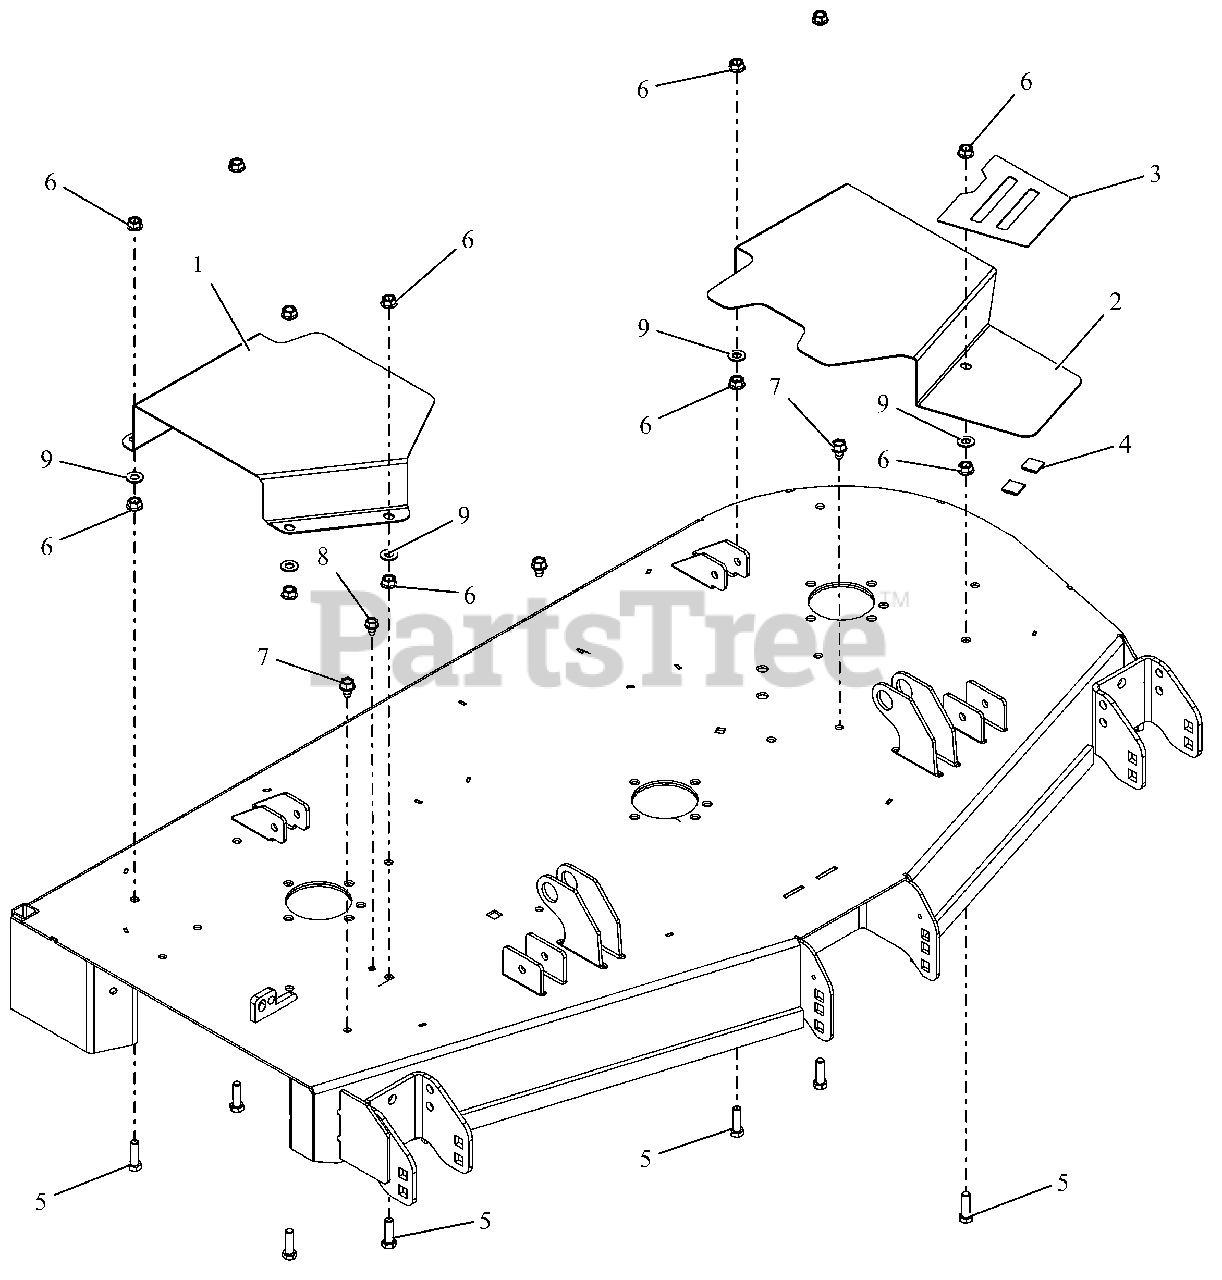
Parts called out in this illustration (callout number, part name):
1	COVER, BELT 52" & 60" RIGHT
2	COVER, BELT 52" LEFT
3	GRIP, TAPE 52-60 BELT COVER
5	@BLT-HEX .38-16X1.25 GR5 YWZC
6	@NUT-SPNLK-FLG .375-16 YWZC
7	@SCR-TAP .38-16X.50 HWH TR YWZ
8	@SCR-TAP .31-18X.50 HWH TR YWZ
9	@WSHR-FL-STL.406X.812X.065 YWZ
